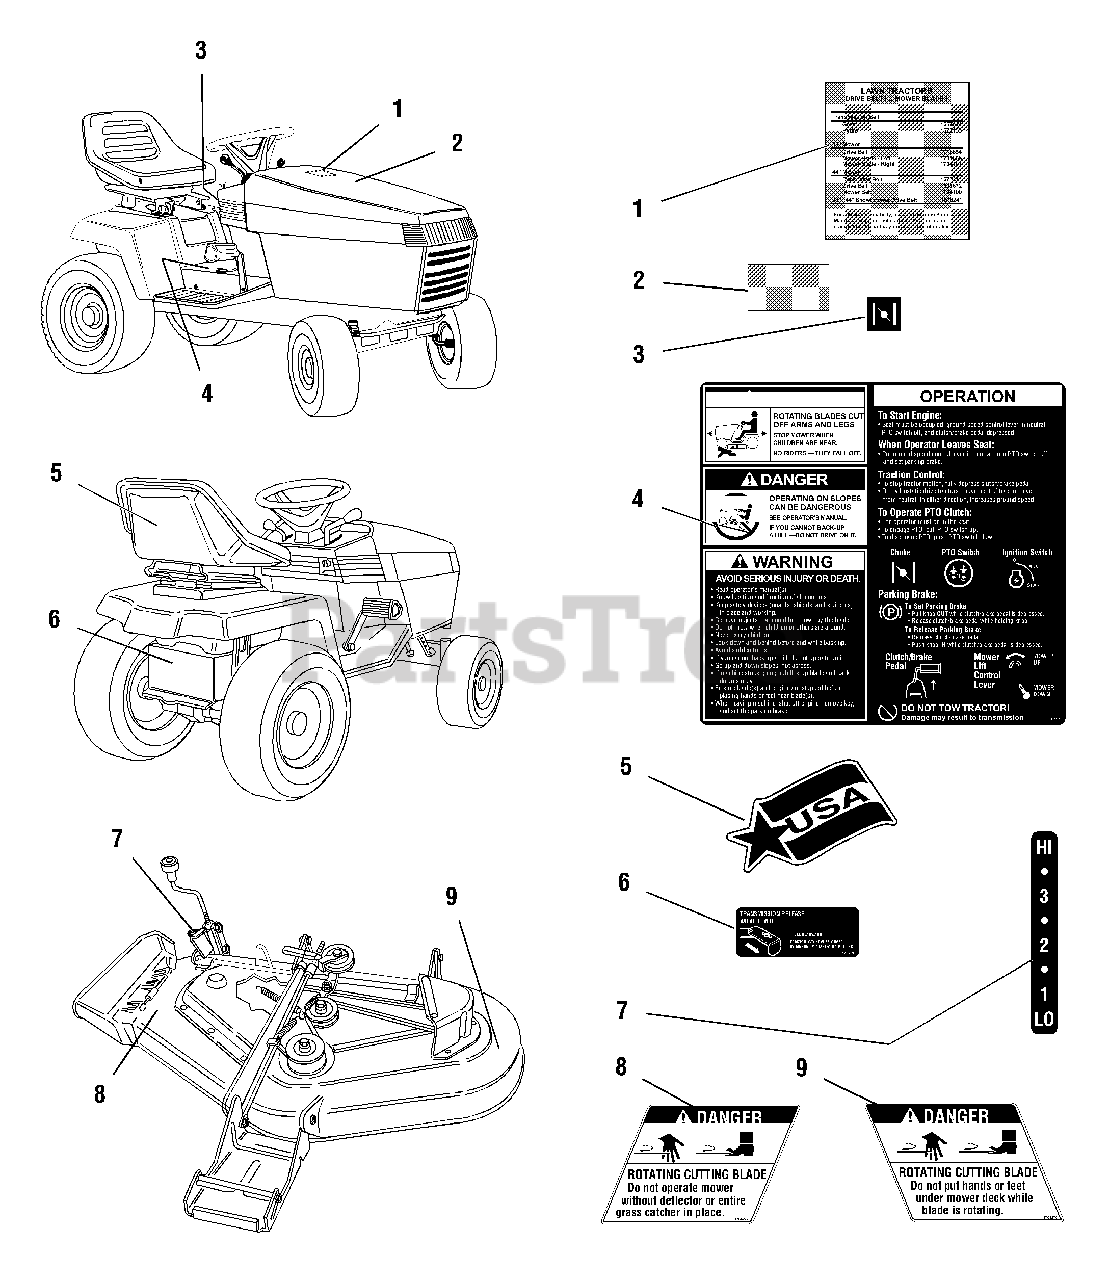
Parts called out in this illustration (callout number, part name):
1	DECAL, Belt, Blade
2	DECAL, Paint
3	DECAL, Choke, Dash (15 HP only)
4	DECAL, Operating Instructions
5	DECAL, USA Logo
6	DECAL, Transmission Release Valve
7	DECAL, Mower Height
8	DECAL, Danger (Chute in place)
9	DECAL, Danger (Hand under deck)
